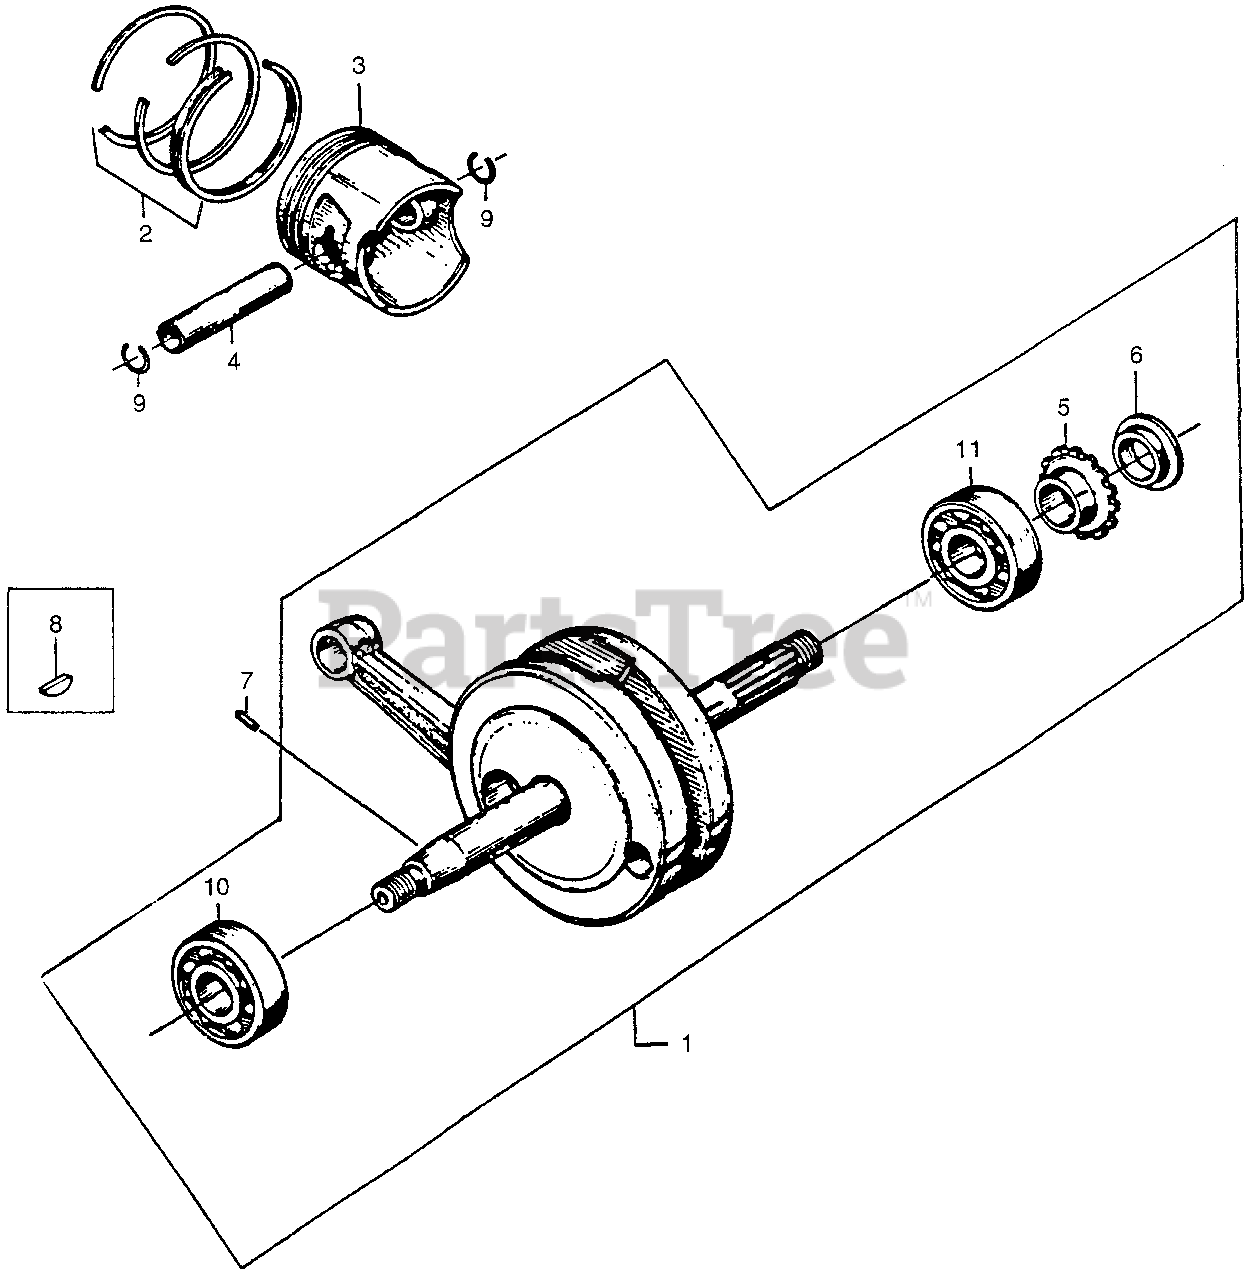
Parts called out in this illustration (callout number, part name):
1	CRANKSHAFT ASSY.
2	RING SET, PISTON (STD)
2	RING SET, PISTON (STD) (NOT AVAILABLE)
2	RING SET, PISTON (OS 0.25)
2	RING SET, PISTON (OS 0.50)
2	RING SET, PISTON (0.75)
3	PISTON (NOT AVAILABLE)
4	PIN, PISTON (NOT AVAILABLE)
5	SPROCKET, TIMING (NOT AVAILABLE)
6	COLLAR, SPROCKET (NOT AVAILABLE)
7	PIN, DOWEL (3X4) (NOT AVAILABLE)
8	KEY, WOODRUFF (3MM)
9	CLIP, PISTON PIN (13MM)
10	BEARING, RADIAL BALL (6203)
11	BEARING, RADIAL BALL (6303)
